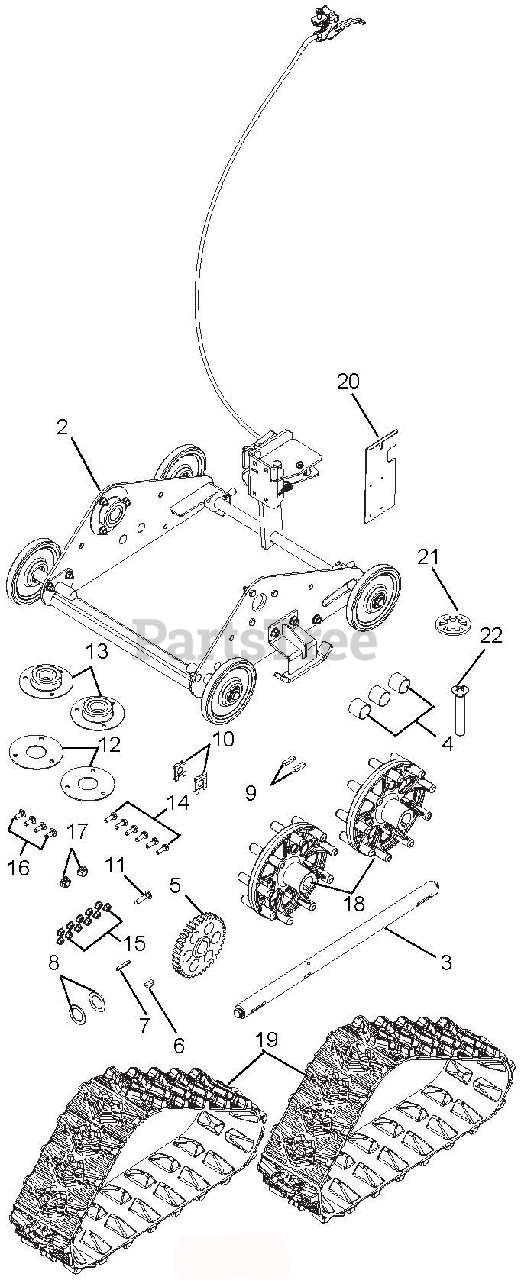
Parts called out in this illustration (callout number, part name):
1	KIT, DLX TRACK SPEED UP
2	DELUXE TRACK CARRIAGE ASSEM.
3	AXLE, TRACK-DELUXE
4	BSHG-SLV, 1.012X1.125X1.00
5	GEAR, SPUR
6	KEY-WDRF .25X.750X.313 SAE91
7	PIN-ROLL .188X1.25
8	WSHR-FL-STL 1.010X1.505X.062YZ
9	KEY-RECT .25X.188X1.00
10	CLIP, SNAP .625 DIA
11	BLT-RDHDXLSQNK.25-20X1.25 G5ZC
12	PLATE, BEARING SPACER
13	BRG-FLG 1.003/1.000 3 BOLT
14	@BLT-HEX .25-20X.75 GR5 YWZC
15	@NUT-LK-TOP-FLG .25-20 YWZC
16	@BLT-RDHDSQNK .25-20X.75 G5YZ
17	NUT-LK-CTR-FLG .38-16 YWZC
18	WHEEL, MACHINED DRIVE
19	TRACK, RUBBER
21	WSHR-LK-INT .250 TH TYA
22	SCR-MCH .25-20X1.50 OVAL HD
